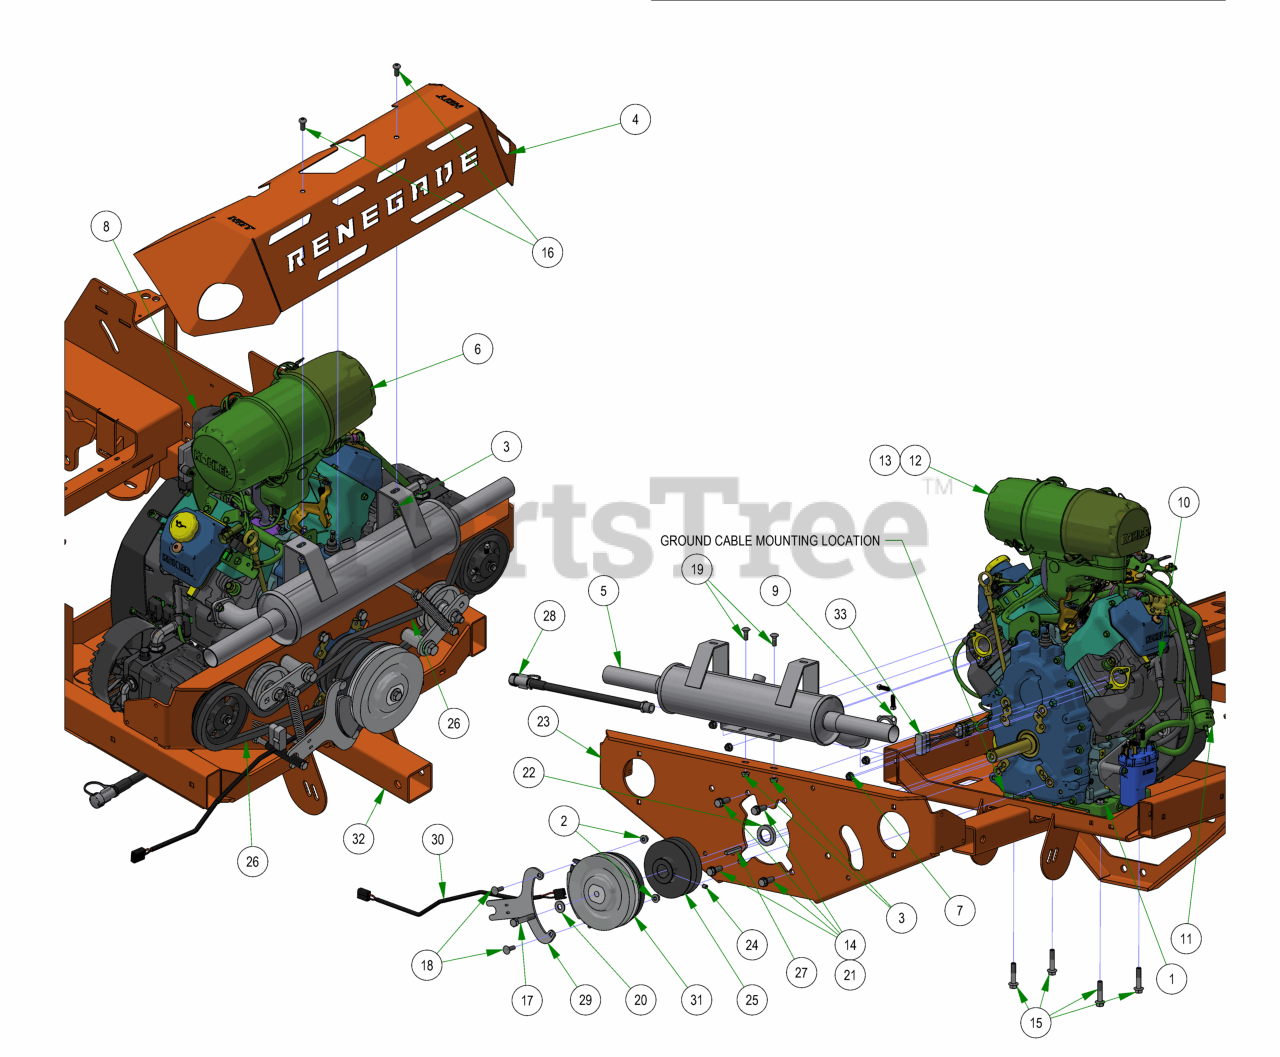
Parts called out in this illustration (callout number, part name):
1	3/8-16 HEX FLANGE TOP LOCKNUT ZINC
2	5/16-18 NYLON INSERT FLANGE LOCKNUT ZINC
3	5/16-18 HEX SERRATED FLANGE NUT HARD/ZINC
4	2023 Renegade Gas Muffler Cover
5	KOHLER ECH980 MUFFLER
6	KOHLER ECH980 ENGINE
7	M8 Nut Connects the 015-1012-00 and the 015-8240-00
8	Kohler ECV/ECH980 OIL FILTER
9	ECV/ECH 980 MUFFLER GASKET
10	Spark Plug - Kohler ECV/ECH 980
11	Universal Inline Fuel Filter
12	Canister Air Filter- Outer
13	Canister Air Filter- Inner
14	7/16-16 x 1 1/4" Hex Bolt GR 5
15	3/8-16x1-3/4 Gr5 Hex Flange Screw Zinc Clear
16	5/16-18 X 3/4 BUTTON SOCKET CAP SCREW 18-8 STAINLESS STEEL
17	7/16-20 X 2-1/2 HEX Bolt GR 8 W/ Patch
18	5/16-18 X 1 CARRIAGE BOLT (GR.8) ZINC
19	5/16-18 X 7/8 CARRIAGE BOLT ZINC
20	3/8 FLAT WASHER USS (1" OD) ZINC
21	7/16 SPLIT LOCKWASHER (GR.8) ZINC YELLOW
22	Horizontal Engine Spacer
23	Pump Plate - 2019 Horizontal Gas-Orange
24	5/16-24 X 3/8 SOCKET SET SCREW (KNURLED CUP PT) PLAIN
25	Outlaw Renegade Double V Pulley
26	2020 Renegade Pump Belt, 42.99"
27	1/4 X 2 SQ MACHINERY KEY 1018 STL PLAIN
28	Kohler 980 Oil Drain
29	2019 Outlaw Renegade Clutch Bracket
30	Clutch Pigtail
31	Clutch for Diesel/Vanguard
32	2019 Renegade Gas Frame - Powdercoated
33	ECH980 Wiring Harness Adapter
